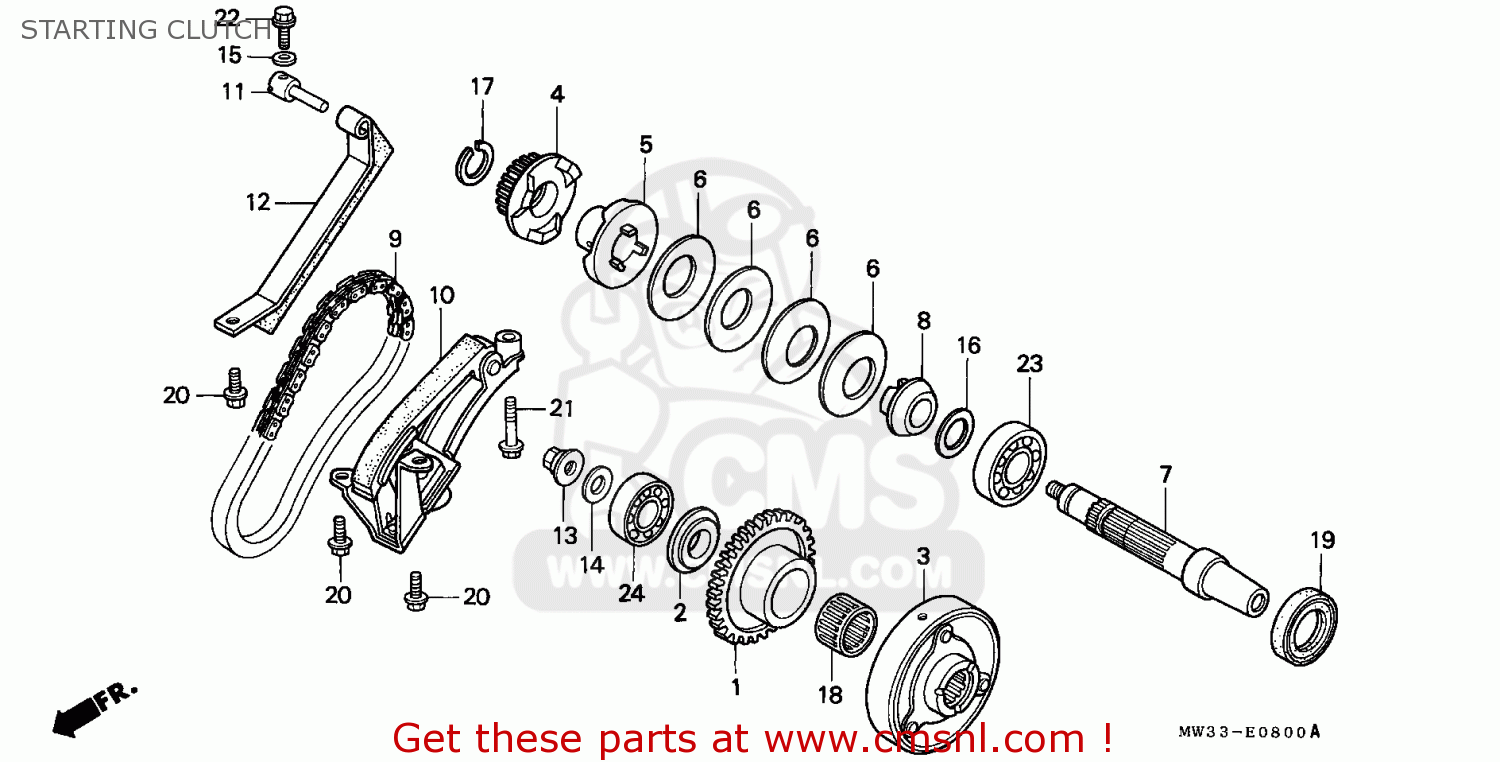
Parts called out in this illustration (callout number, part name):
1	GEAR ST/CLUTCH
2	P/L START CLUTCH
3	OUTER COMP.,START
4	SPROCKET,A.C.GENE
5	CAM DAMP,ACG DRIV
6	SPG,ACG DAMPER
7	SHAFT,A.C.GENERAT
8	COLLER,20MM
9	CHAIN,A.C.GENERAT
10	TENSIONER ASSY.,A
11	PIN ACG TENS,SPG
12	GUIDE,ACG CHAIN
13	NUT,FLANGE 10MM
14	WASHER 10X22
15	WASHER,SEALING,6.
16	SHIM F,3RD GEAR,F
17	CIR CLIP,20MM
18	NEEDLE BRG
19	OIL SEAL,26X42X8
20	BOLT,FLANGE,6X14
21	BOLT,FLANGE,6X25
22	BOLT,FLANGE,SH 6X18
23	B/BRG RAD N/COM
24	B/BRG RAD N/COM
